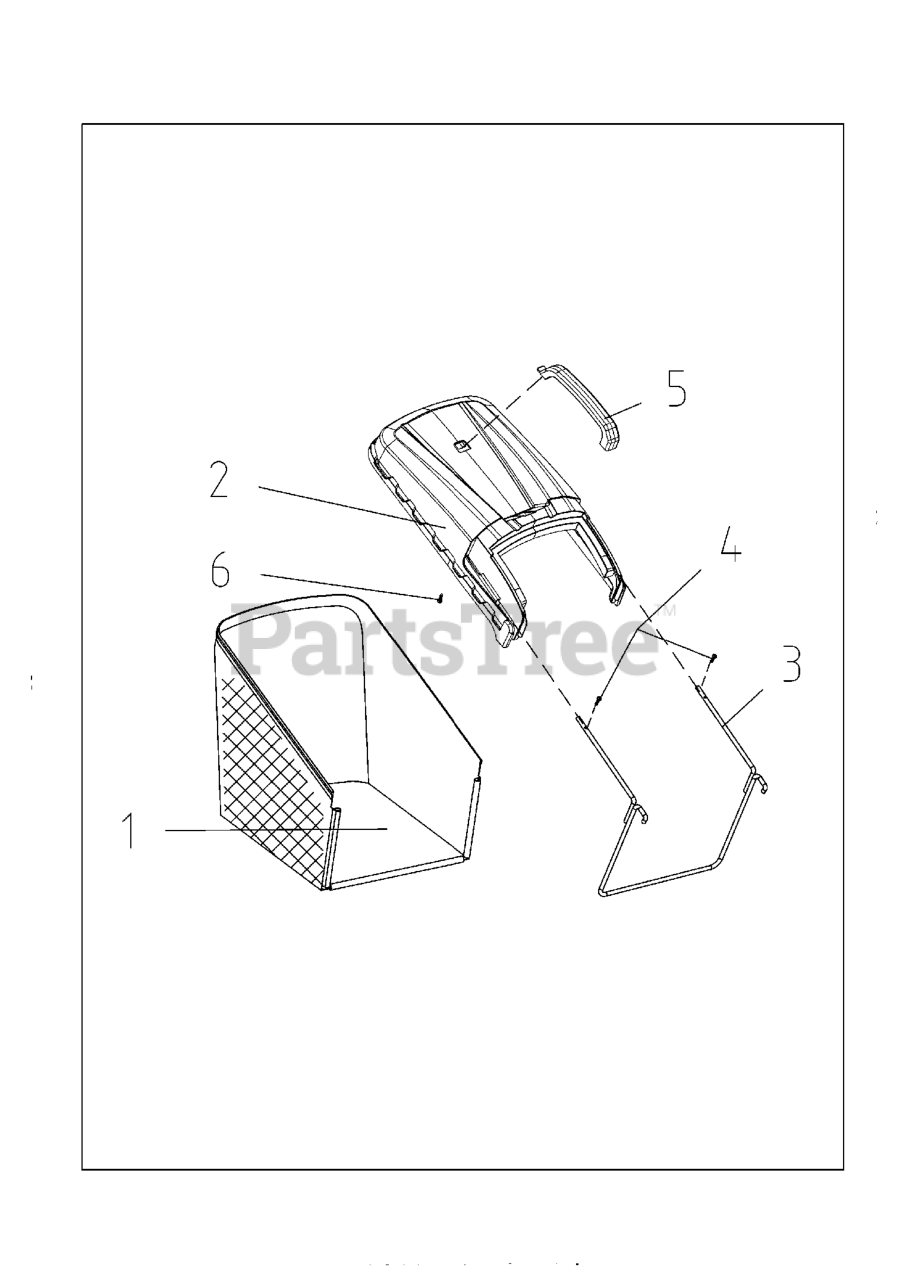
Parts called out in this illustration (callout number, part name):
1	GRASSBAG #25100173001
2	COVER GRASS CATCHER #253417001
3	BRACKET #26300299201
5	HANDLE #25341800101
6	SCREW ST4.8*19,GB845 #26800104
